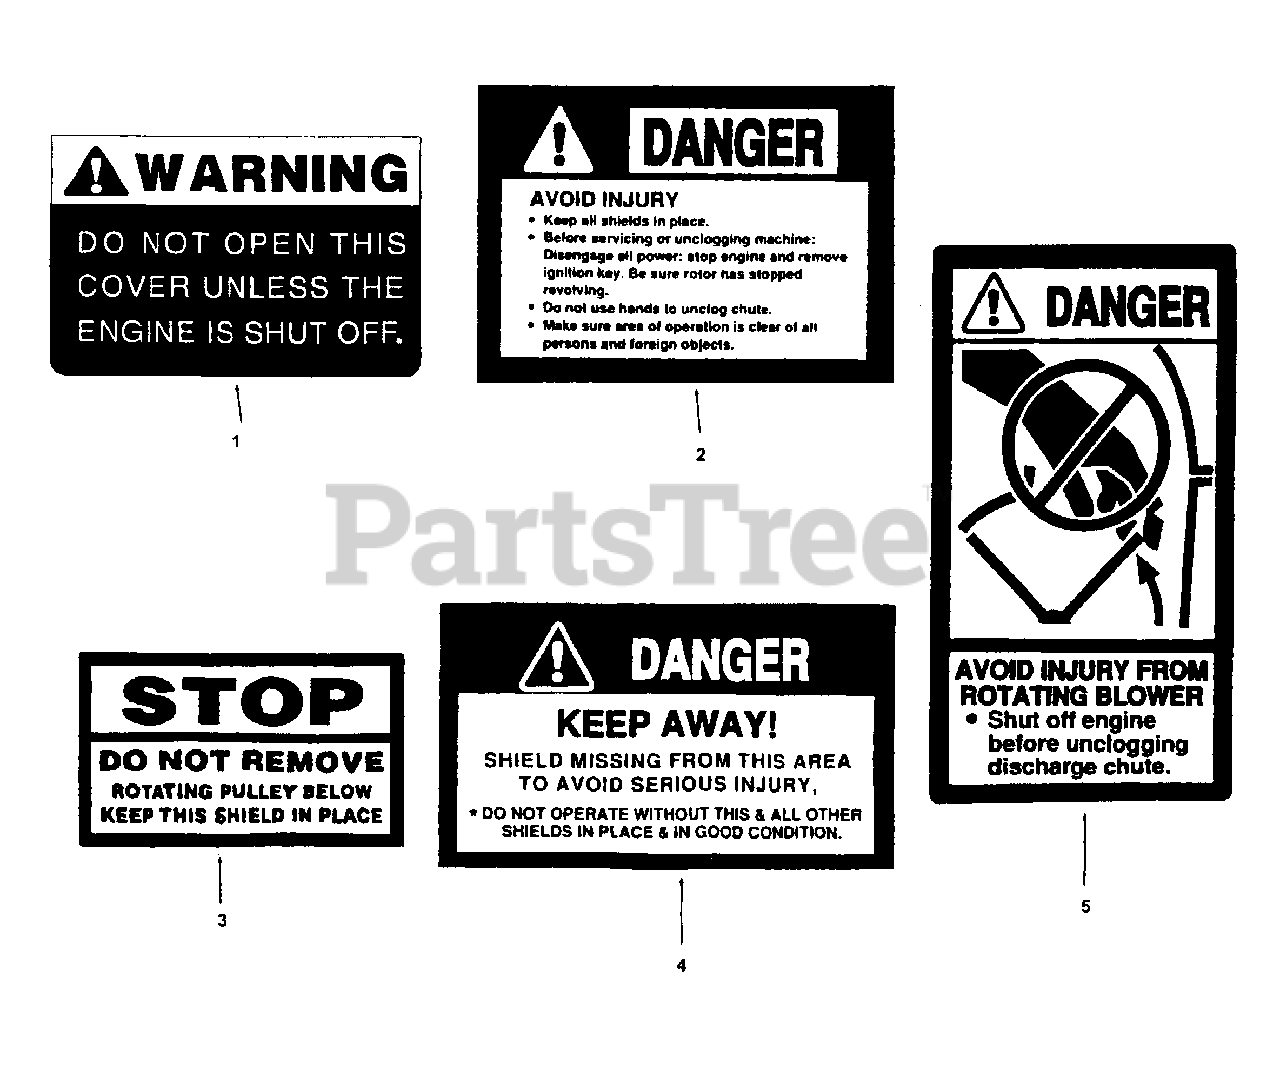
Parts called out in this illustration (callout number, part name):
1	Bagger Cover Decal
2	Top of Belt Shield Decal
3	Don't Remove Decal
4	Danger Shield Missing Decal
5	Danger Implr. Decal
